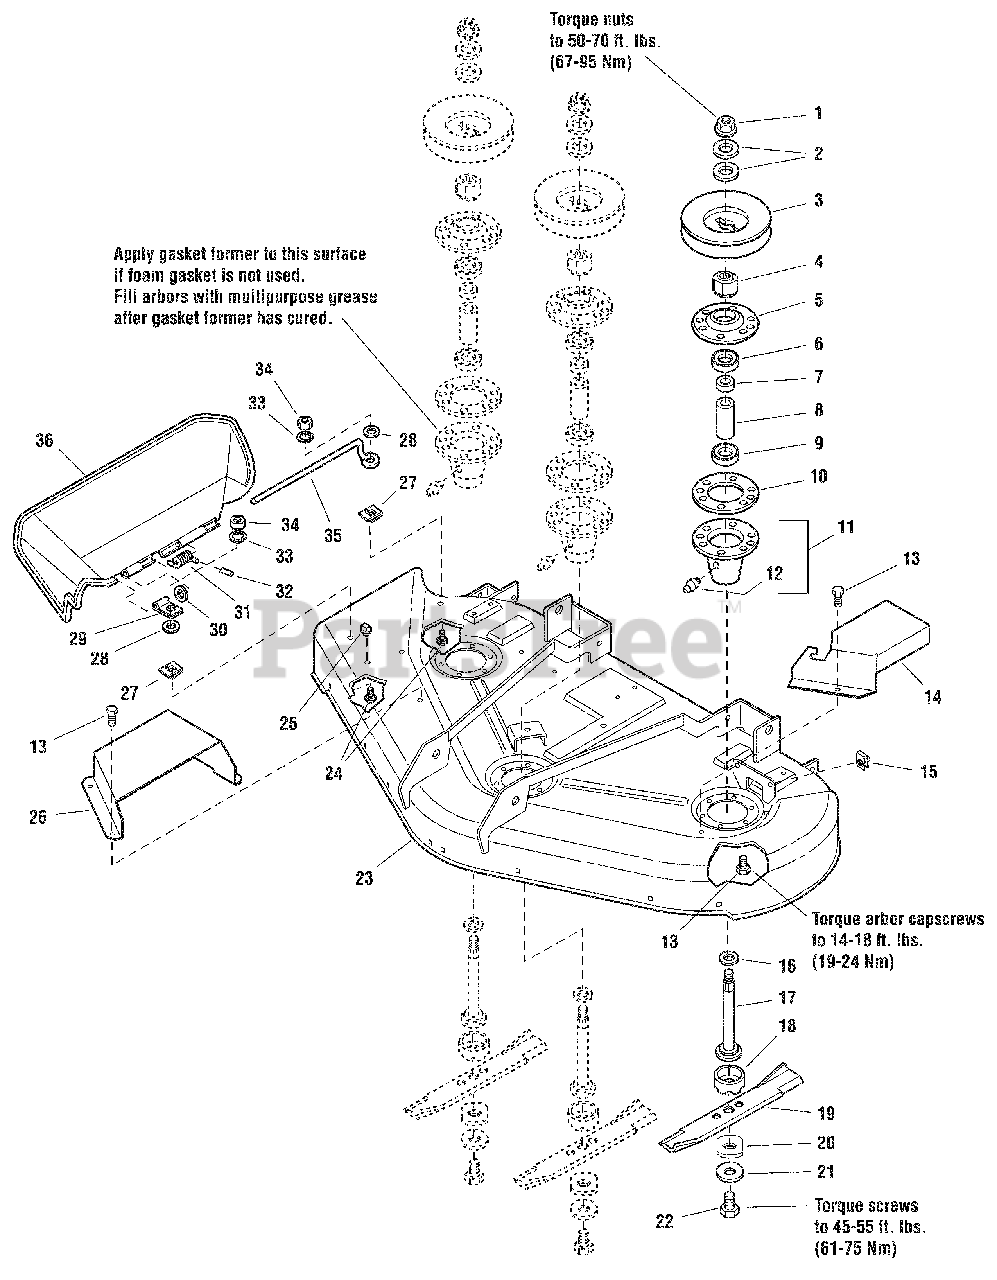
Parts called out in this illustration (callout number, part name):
1	NUT, HEX FLANGE 9/16-18 YEL (NON LOCKING)
2	WASHER, Bellville, 9/16
3	PULLEY
4	HUB, .681ID 1.50 OD 1.24 LG SERRAT ID PM
5	HOUSING, ARBOR, TOP
6	BEARING, BALL 0.750ID 1.780OD 0.610LG
7	SPACER, 21/32x3/4x5/8
8	SPACER, 0.688IDX1.000ODX2.679LG PWDR MTL
9	BEARING, BALL 11/16X1-9/16X15/32
10	GASKET, FOAM POLY .12THK 1.00ID 3.75OD
11	ARBOR HOUSING ASSY, BOTTOM
12	FITTING, LUBE .250 DRIVE .25SH BL CHK YEL
13	CAPSCREW, Hex Washer Head Taptite, 5/16-18X0.750BLK
14	GUARD, BELT - LH
15	BODY CLIP, 5/16-18-7GA MATERIAL
16	WASHER, CUPPED HEAT TREAT
17	SHAFT, ARBOR W/EXTRUDED WASHERS 6.50LG
18	SHIELD, GRASS, LOWER, HEAT TREAT
19	BLADE, 18-1/8 50"DECK BLACK
20	WASHER, HEX, YELLOW ZINC
21	WASHER, SPRING 0.475IDX1.75ODX.156TH BLK
22	CAPSCREW, HEX HEAD 7/16-14x1-1/4 G8 YELLO
23	DECK SHELL, W\DECALS, 375ZB2050 (S/N: 2013371638 & Below)
23	DECK SHELL W/ DECALS, 375ZB2050 (S/N: 2013371639 & Above)
24	BOLT, RD HD SH SQ NK 1/4-20X0. 875 G5 BLK
25	PLUG, BUTTON FOR 0.344SQ HOLE BLACK POLY
26	GUARD, BELT - RH, 44", SNAPPER RED
27	NUT, PUSH FOR .250 DIA THREAD .500 OD BLK
28	WASHER, 0.250(0.26IDX0.84ODX.12THK) YEL
29	CLAMP, WIRE, .312DIA . (1) .281 HOLE BLK
30	WASHER, 0.312 (0.34IDX0.75ODX.06THK) BLK
31	SPRING, TORSION CHUTE 44/50" BLK
32	CAP, SPRING END .093ID .75LG BLACK VINYL
33	LOCKWASHER, SPRING .250 BLK
34	NUT, HEX 1/4-20 BLK 588514
35	ROD, DEFLECTOR
36	DEFLECTOR, BLACK PLASTIC 30">50" DECKS
